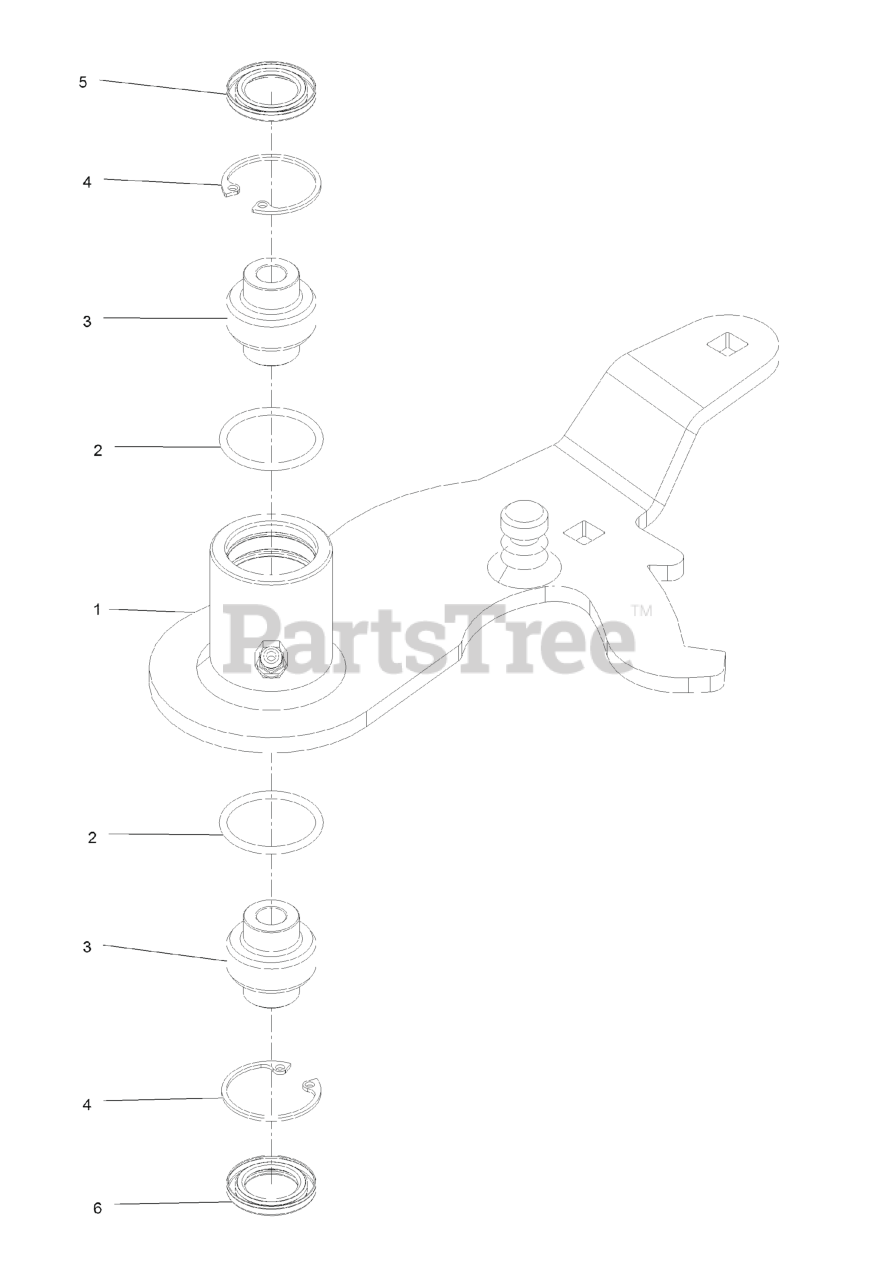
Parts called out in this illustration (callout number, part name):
1	ASM-Idler Arm 96Rd LH [red]
3	BEARING-SPHERICAL
4	RING-SNAP
5	SEAL-LIP, SINGLE
6	SEAL-LIP, DOUBLE
